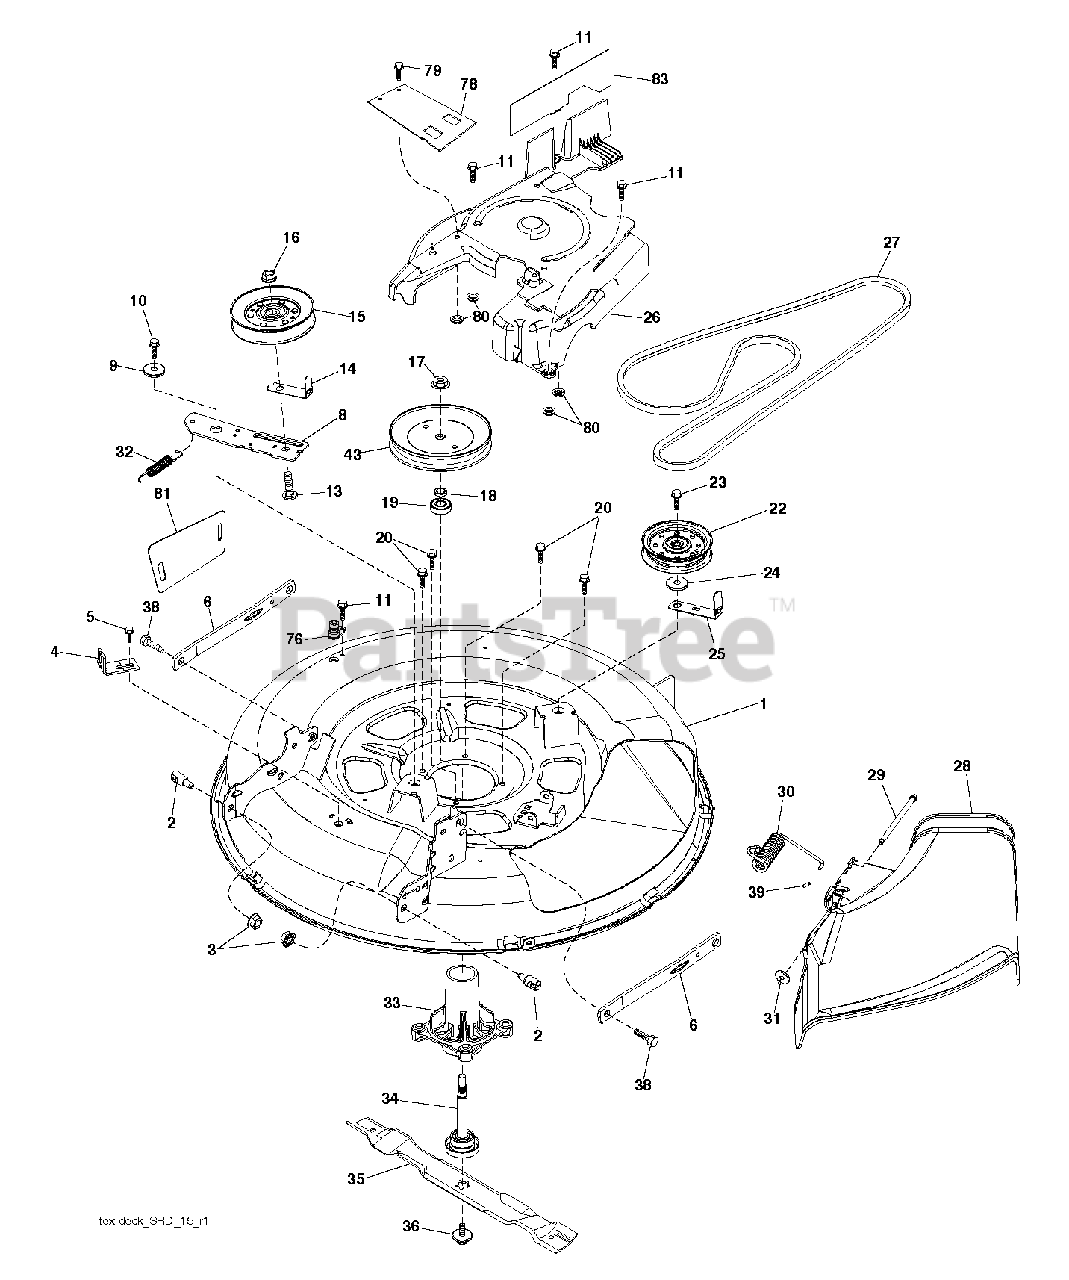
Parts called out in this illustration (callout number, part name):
2	STUD.FASTNER.W/ANTI-ROTATE
3	NUT LOCK HEX FLANGE 5/16-18
5	BOLT.5/16HEX.WHS.HD
6	ARMS.SUSP.MOWER.REAR.SRD
9	SPACER.RETAINER
10	SCREW 3/8-16X1
11	SCREW.1/4-20X5/8
13	BOLT.3/8-16X1.50
14	KEEPER, BELT IDLER
15	PULLEY.IDLER.4.25
16	NUT LOCK FLG 3/8-16 UNC
17	NUT.FLANGE.LOCK.TOP
18	WASHER.SPACER.MANDREL
20	SCREW, WASHER HEAD
22	PULLEY.IDLER.FLAT.UNPLATED
23	SCREW LT
27	V-BELT.DRIVE.MOWER.30"
28	SHIELD.DEFLECT.MWR.30S.BLACK
30	SPRING.TORSION.DEFLECT
31	NUT PUSH M
32	SPRING.MOWER.DRIVE.ELECTRIC
33	HOUSING MANDREL
34	SHAFT.ASM.MDRL.N/GREASE.38
35	BLADE, MULCH.LRV30
36	BOLT.WASHER.ASM.7/16-2
38	BOLT.SHOULDER
39	CAP-SLEEVE LT
43	PULLEY, MANDREL 6.5 PD
76	PORT.WASHOUT
79	SCREW.HI-LO.CONSOLE
80	PALNUT 1/4
